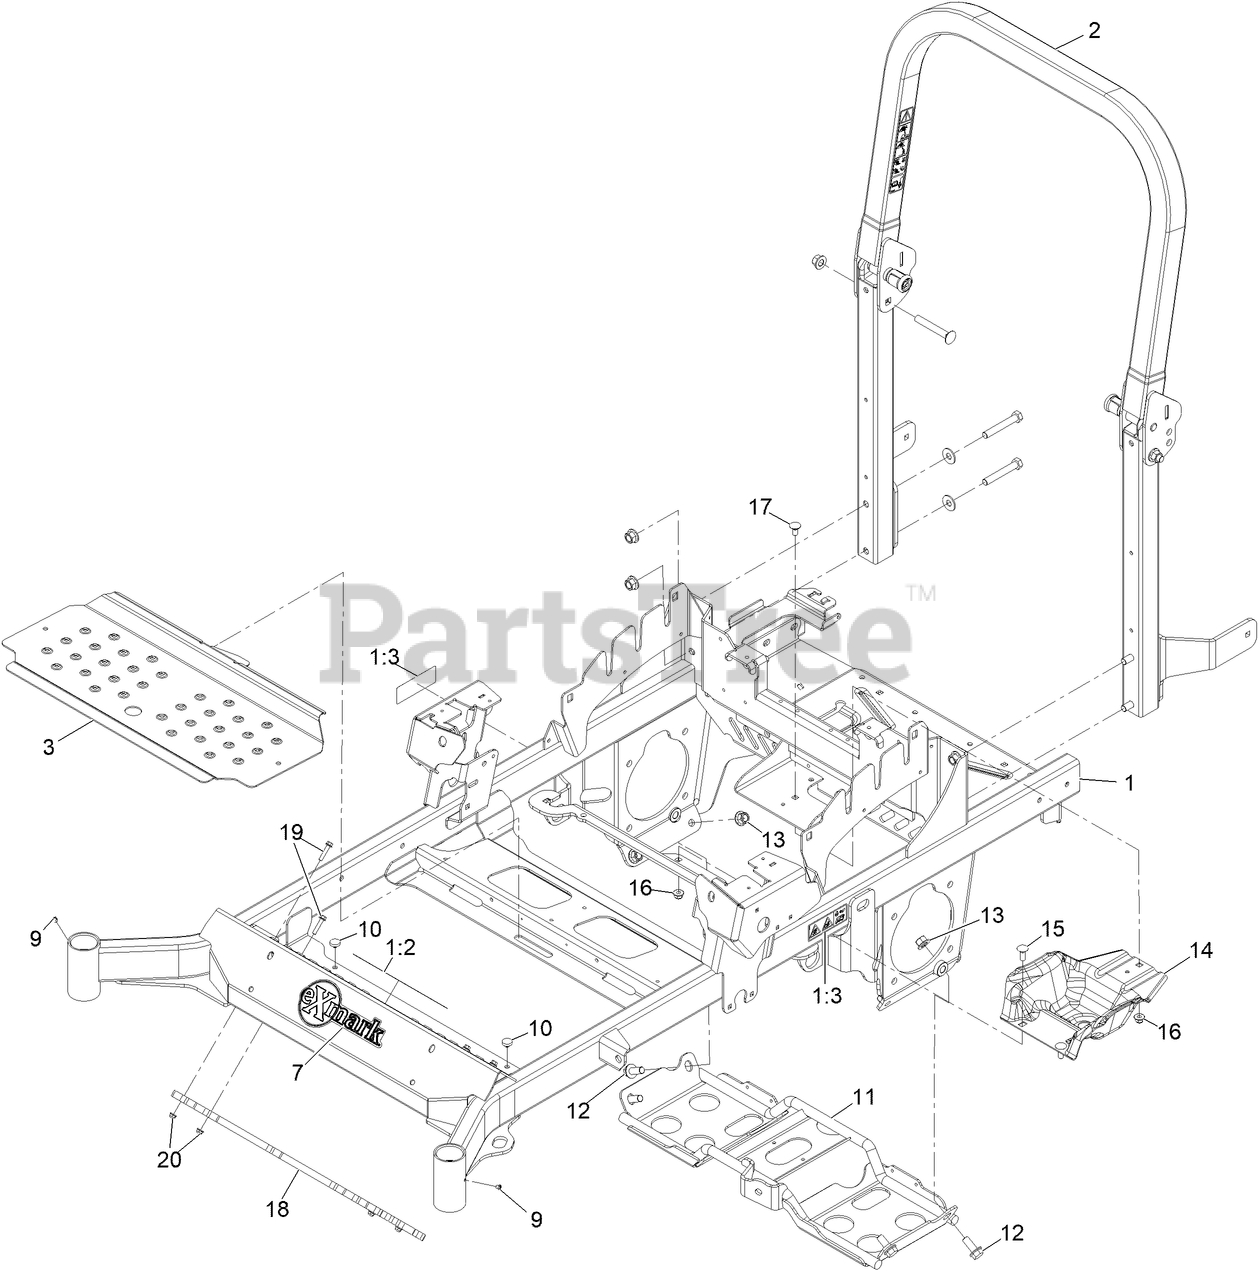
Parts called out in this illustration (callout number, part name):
1	Mainframe Service ASM
1:2	DECAL-DANGER
1:3	DECAL-WARNING
2	ASM, ROPS
3	Pan, Floor
7	DECAL-EXMARK
11	Weld, Skid Plate
12	SCREW-HHF
13	Nut-Lock 1/2-13
14	Guard-Sump
15	Screw-CARR
16	NUT-HF, NI
17	SCREW-CARR
18	Weight-Toe Board
19	SCREW-HHF
